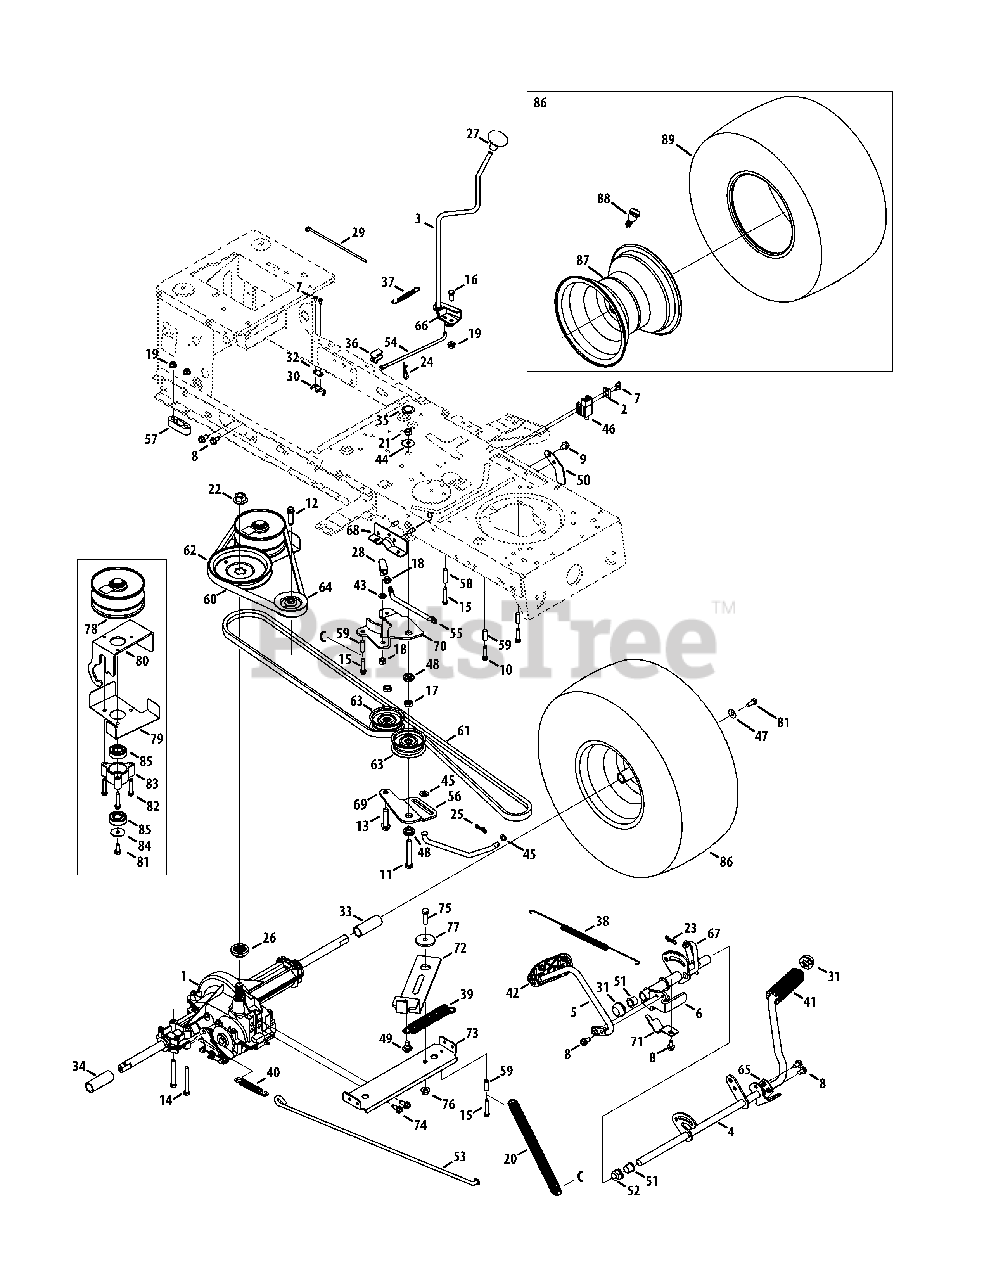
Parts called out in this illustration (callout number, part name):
1	Drive Asm, autodrive Lt-5
2	Plate Switch
3	Lever Asm, shft
4	Pedal Asm, drive, autodrive Lt-5
5	Pedal Asm, cont, autodrive Lt-5
6	Bracket Asm, pedal, autodrive
7	Screw, ab, #8-18, 0.500, Hxindwsh
8	Screw, tt, 5/16-18, .750, Hxindwsh
9	Screw, tt, 5/16-18, 0.625, Hxindwsh
10	Screw, tt, 1/4-20, 1.250, Hxindwsh
11	Hhcs, 3/8-16, 2.50, Gr5, Std
12	Screw, ttsems, 3/8-16, 1.500, Hxlwsh
13	Screw, tt, 3/8-16, 1.750, hxindwsh
14	Hhcs, 5/16-18, 3.50, Gr5, Std
15	Screw, tt, 1/4-20, 1.625, Hxindwsh
16	Hhcs, 5/16-18, .75, Gr5, Std
17	Nut, jam, 7/16-20, Gr2
18	Nut, hex, 3/8-24, Gr5
19	Nut, flglk, 5/16-18, Grf, nylon
20	Spring, extn, .56 x 12.05 x .068
21	Nut, hexlck, 3/8-16, cntrlck
22	Nut, flg, 9/16-18, Gr2
23	Pin, cot, 3/32, 1.0
24	Pin, cotter Int- .125 Dia
25	Pin, cot, bow-Tie 72
26	Hub, pul, 5/8 Spline
27	Knob, shft
28	Ball, joint
29	Cbl, tie, 3/16 X .05 X 7.4
30	Switch, Spring, short
31	Cap, push 5/8
32	Plate, Insulator Nut
33	Sleeve, .758 X .821 X 3.3125
34	Sleeve, .758 X .821 X 2.4375
35	Plug, deck Hole, 7/8
36	Bearing, plt;Shift
37	Spring, ext, .38 Od X 3.25 Lg
38	Spring, extn, .70 Dia X 12.00 Lg
39	Spring, extn, .97 Od X 6.18 Lg
40	Spring, extn, .59 Od X 4.00 Lg
41	Pad, foot, 4.0 Long
42	Pad, cont
43	Washer, lock, 3/8, Regular Duty
44	Washer, Flat, .406 x 1.920 x .060
45	Washer, flat, .375 X .738 X .063
46	Switch Interlock
47	Bell Washer, .340 x .872 x .060
48	Spacer, shldr, 1.00 X .38 X .38
49	Screw, shldr, .43x.29, Tt, 5/16-18
51	Bearing, flg, .630 Idx .695 Od X .60
52	Bearing, hex Flg, .628 Id, split
53	Rod, brake, lt-5 Trans
54	Rod, shift, lt-5 Stretch 46"
55	Rod, adj, idlr, 3/8
56	Rod, trans, footpedal Bypass
57	Spacer, T-Axle .68
58	Spacer, .260 X .372 X 1.420 Lg
59	Spacer, .260 X .375 X 1.030 Lg
60	Belt, v Typ, 5l X 40.9 Lg Poly
61	Belt, v Typ, 5l, 90.93, Poly
62	Pulley, v Typ, 7.25 Dia Spun
63	Pulley, idlr, flat 2.75 Od
64	Pulley, idlr, v-Type X 3.06
65	Bracket, ped, support Lt-5
66	Bracket, shft, adj
67	Plt, Bracket, reinforcement
68	Bracket, pedal, frame Rh
69	Bracket, idlr, center Dbl
70	Bracket, idlr, dbl Autodrive Lt-5
71	Bracket, supt, pedal Stap
72	Bracket Asm, idlr
73	Bracket Asm, autodrive Lt-5
74	Screw, tt, 5/16-18, 0.750, Hxindwsh
75	Hhcs, 3/8-16, 1.25, Gr5, Std
76	Nut, flglk, 3/8-16, Grf, nylon
77	Spacer, shldr, .8840 X .190
78	Pulley Asm, var Spd, 4.75 Od
79	Keepr Asm, belt
81	Hhcs, 5/16-24, .750, Gr5, Lock
82	Screw, tt, 1/4-20, 1.500, Hxindwsh
83	Cup, brg
84	Washer, flat, .330 X 1.25 X .06, Ht
85	Bearing, ball, 17x40x12, 6203, Ds
86	Wheel, 20 x 8 x 8
87	Rim Asm 8.0 X 7.0 X .750 Id
88	Valve, tubeless Air
89	Tire, 20 X 8 X 8 Sq Sh
